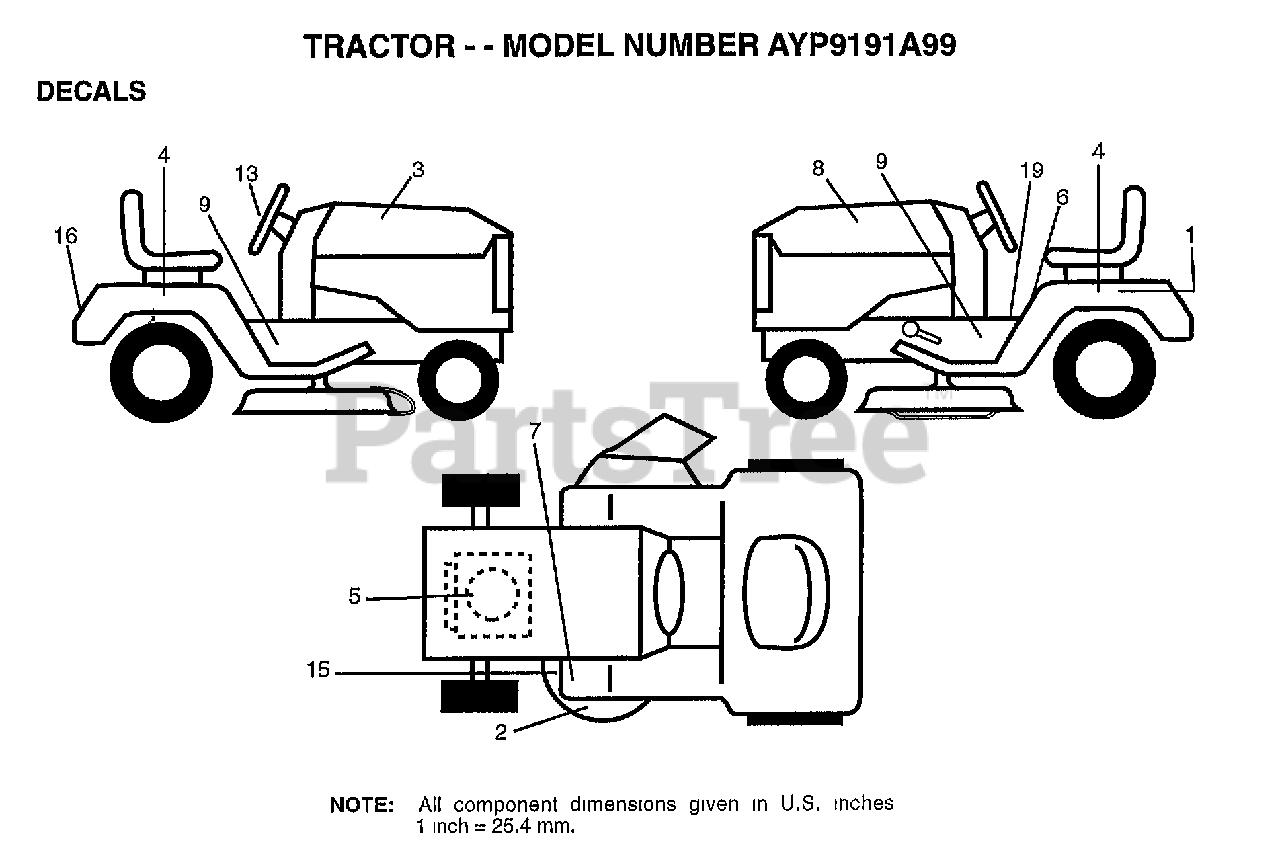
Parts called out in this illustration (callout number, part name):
1	DECAL.BATRY.3-3908
2	DECAL DECK WIZ +
3	DECAL.HOOD.RH
4	DECAL.FENDER.WIZ
6	"DECAL DANGER,FEND"
8	DECAL.HOOD.LH
9	"DECAL.CHASSIS.42"""
13	DECAL.INS.STRG.WL
15	"DECAL-SCHEM,BELT"
19	"DECAL INST,SADDLE"
